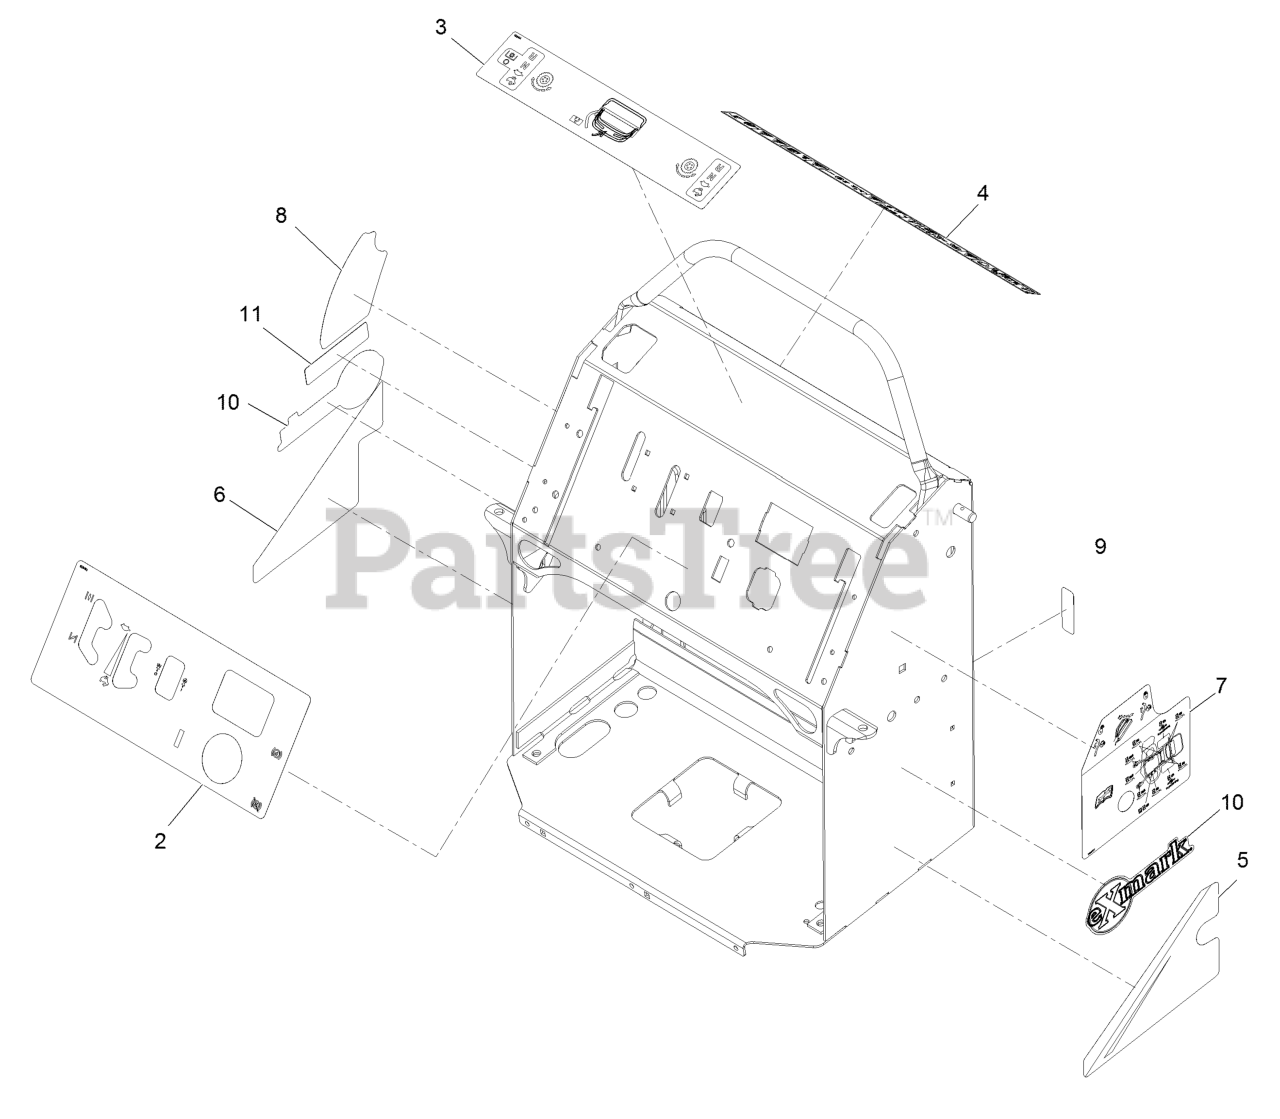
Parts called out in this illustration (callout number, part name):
2	Decal-Control Panel
3	Decal-Motion Control
4	Decal-Warning
5	Decal-LH Panel
6	Decal-RH Panel
7	Decal-Service Aid
8	Decal-Height Of Cut
9	Decal-Fuse
10	Decal-Exmark Logo
11	Decal-Arrester, Spark
